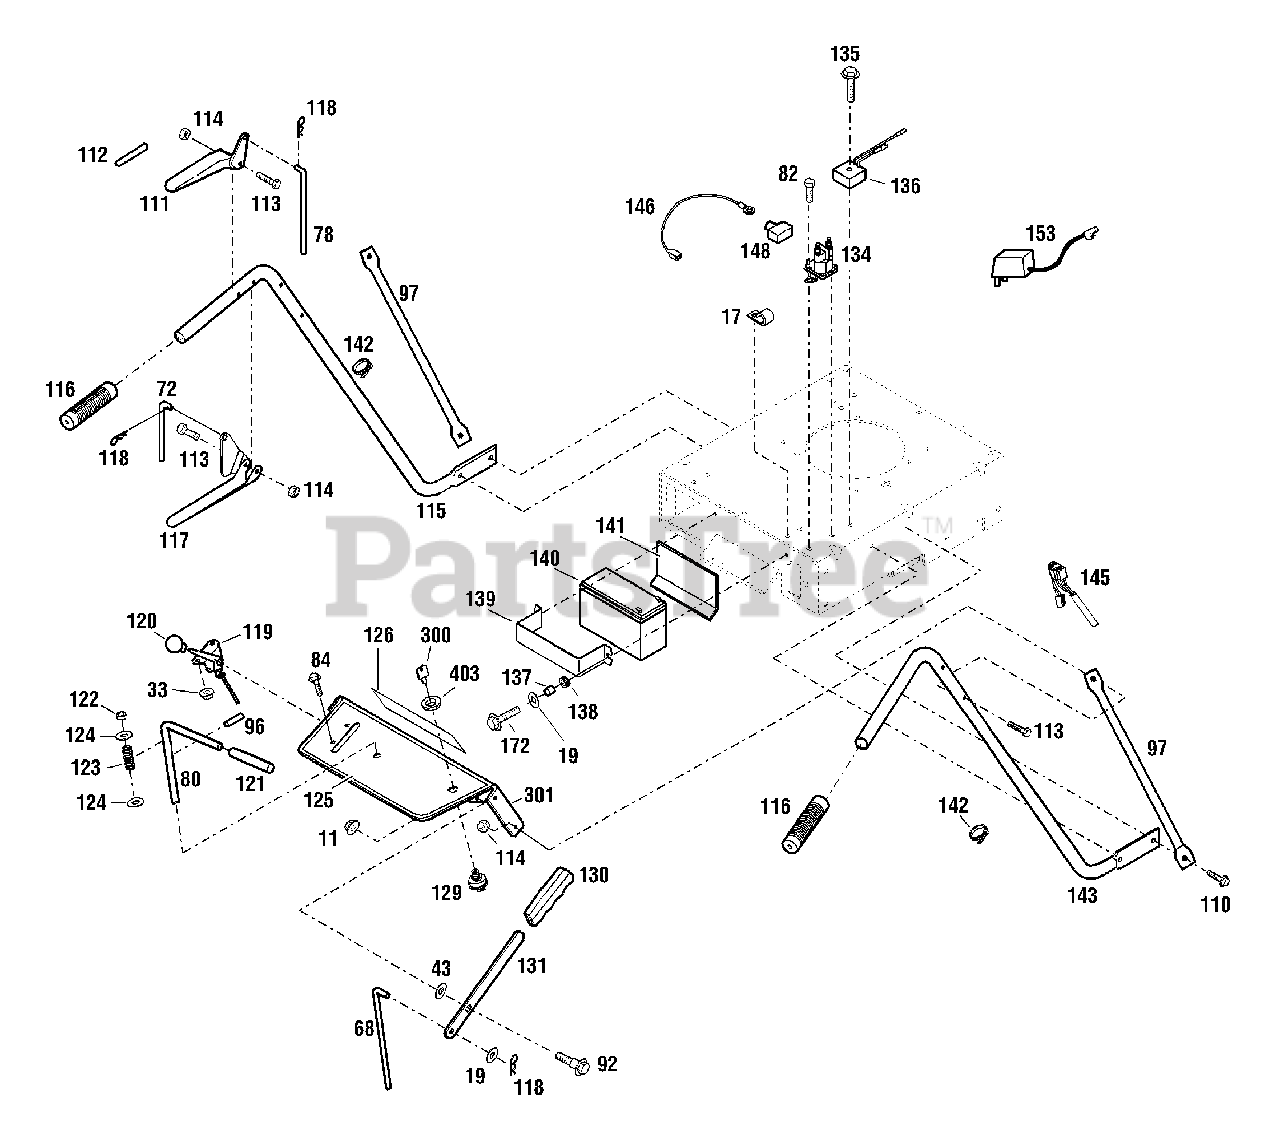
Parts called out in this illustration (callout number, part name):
11	Flange Locknut, 3/8-16
17	J-Clip
19	Flat Washer, 5/16
33	Flange Locknut, 1/4-20
43	Flat Washer, 1/2
68	Upper Blade Rod
72	Upper Transmission Rod
78	Upper Brake Rod
80	Shift Rod
82	Thread Cut. Screw, 1/4-20 x 1/2
84	Flange Lock Screw, 1/4-20 x 1/2
92	Shoulder Bolt
96	Roll Pin, 1/4 x 2-1/4
97	Brace, Handlebar
110	Flange Lock Screw, 5/16 x 3/4
111	Control Handle
112	Operator Presence Control Decal
113	Screw, 1/4-20 x 1-3/4, Grade 8
114	Locknut, 1/4-20
115	Left Handlebar
116	Handle Grip
117	Control Handle
118	Hair Pin, 5/64
119	Throttle Control
120	Knob
121	Handle Grip
122	Nylon Bushing
123	Compression Spring
124	Flat Washer, 1/2
125	Warning Decal
126	Logo Decal
129	Ignition Switch
130	Handle Grip
131	Mower Engage Lever
134	Solenoid
135	Thread-Cut. Screw, 1/4-20 x 1-1/2
136	Regulator
137	Spacer
138	Grommet
139	Battery Bracket
140	Battery
141	Battery Pad
142	Plastic Tie
145	Wiring Harness
146	Lead
148	Boot
153	Battery Charger (shipped loose)
172	Screw, 5/16-18 x 3/4"
300	Ignition Key
301	Console Assembly
403	Nut, Ignition Switch
